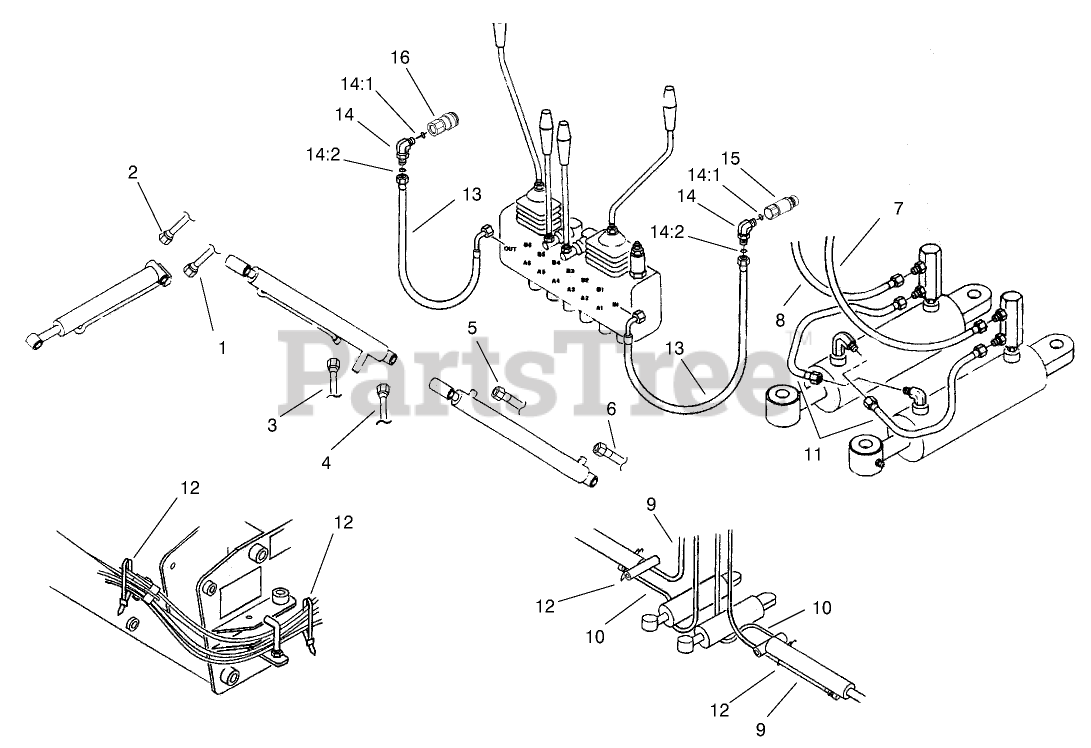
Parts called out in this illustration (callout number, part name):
1	HYD HOSE ASM
2	HYD HOSE ASM
3	HYD HOSE ASM
4	HYD HOSE ASM
5	HYD HOSE ASM
6	HYD HOSE ASM
7	HYD HOSE ASM
8	HYD HOSE ASM
9	HYD HOSE ASM
10	HYD HOSE ASM
11	HYD HOSE ASM
12	TIE-CABLE
13	HYD HOSE ASM
14	FITTING-ELBOW 90
14:1	O-RING
14:2	O-RING
15	NIPPLE-CONNECT, PRESSURE
16	COUPLER-FACE, FLUSH
